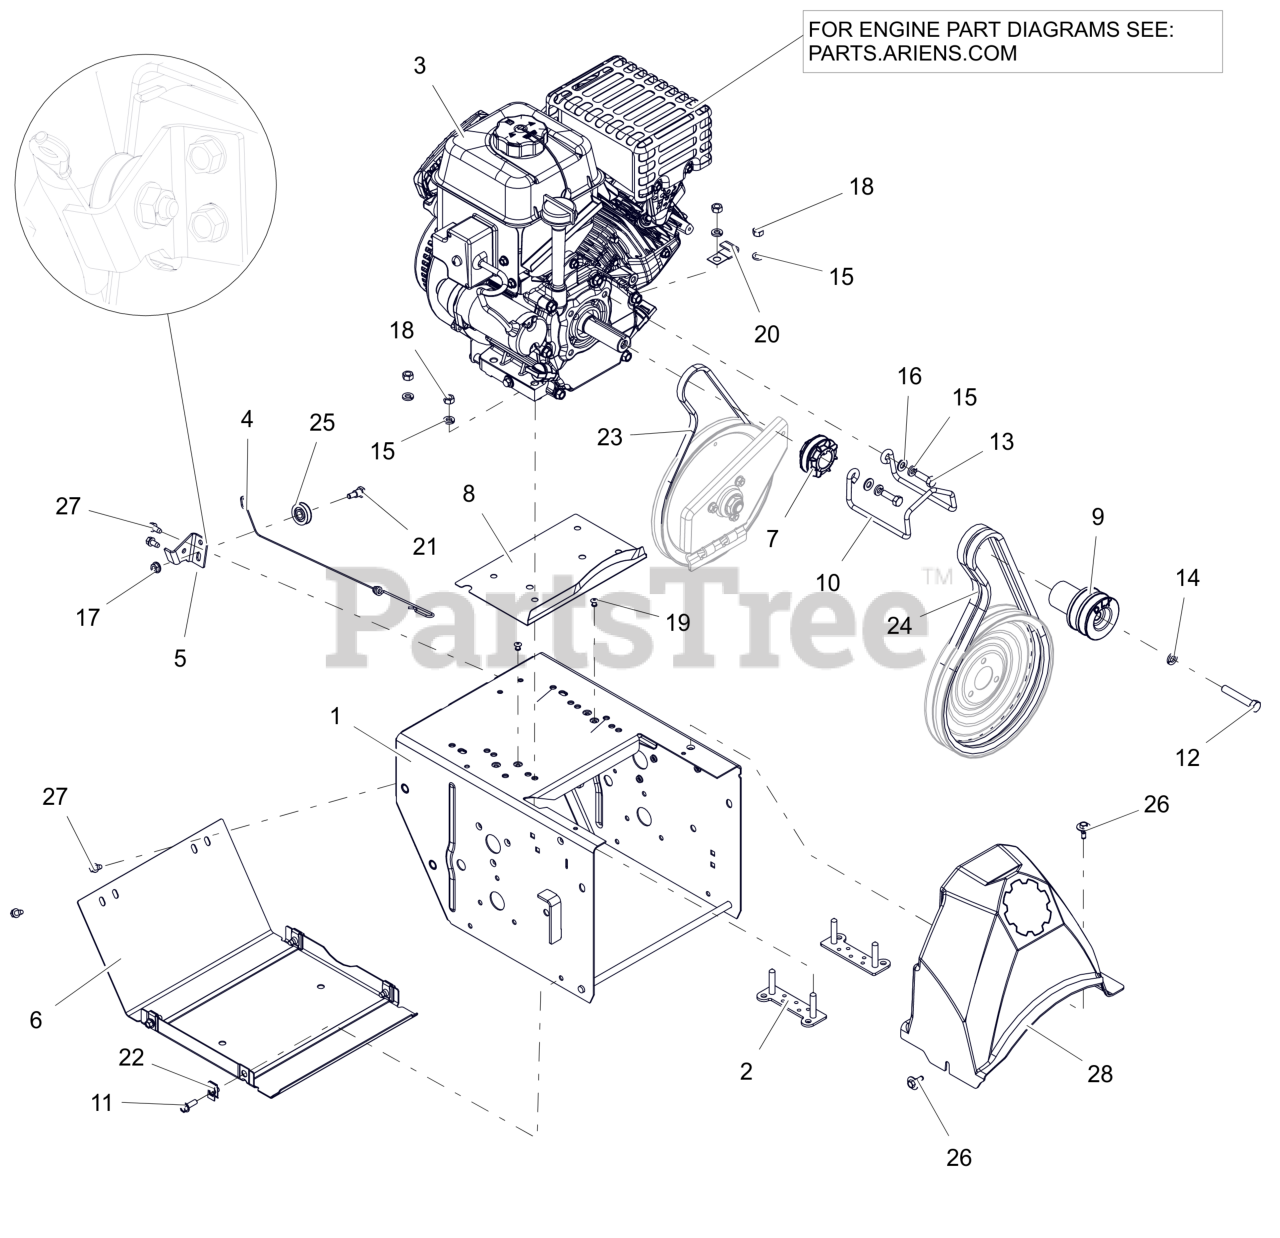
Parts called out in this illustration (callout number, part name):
1	FRAME, MAIN - 14GA DELUXE (ORANGE)
2	STRAP, BOLT - SMALL ENGINE
3	ENGINE, ARIENS AX254 240V/60W
4	CABLE, LOWER TRACTION,SS & PRO
5	BRKT, CABLE PULLEY
6	COVER, BOTTOM
7	SHEAVE, DRIVE
8	BAFFLE, WATER-SMALL
9	SHEAVE, ATTACHMENT - STANDARD 2 GRV
10	FINGER, BELT
11	BLT, HWH .25-20X.75 G5 ZCC
12	BLT, HEX .38-24X2.25 G5 ZCC
13	BLT, HEX 0.3125-24X1 G5 ZCC
14	WSHR,LK-REG .375X.094 ZCC
15	WSHR, LK-HVY .312X.097 ZCC
16	WSHR,FLT .344X.688X.065 ZCC
17	NUT-LK-TOP-FLG .250-20 GF ZCC
18	NUT, HEX .312-18 ZCC
19	RVT, POP .1875 ZCC
20	J-CLAMP
21	BOLT, SHLDR -.375 X .375 X .25-20
22	NUT-RTNR .25-20X.56
23	V-BELT, 3L-WRAPPED
24	V-BELT, HA-RAW EDGE (SET)
25	PULLEY, CABLE
26	SCR-TAP .25-20X.5 CAPTIVE
27	SCR-TAP .25-20X.50 HWH ZCC
28	COVER, BELT - SMALL
